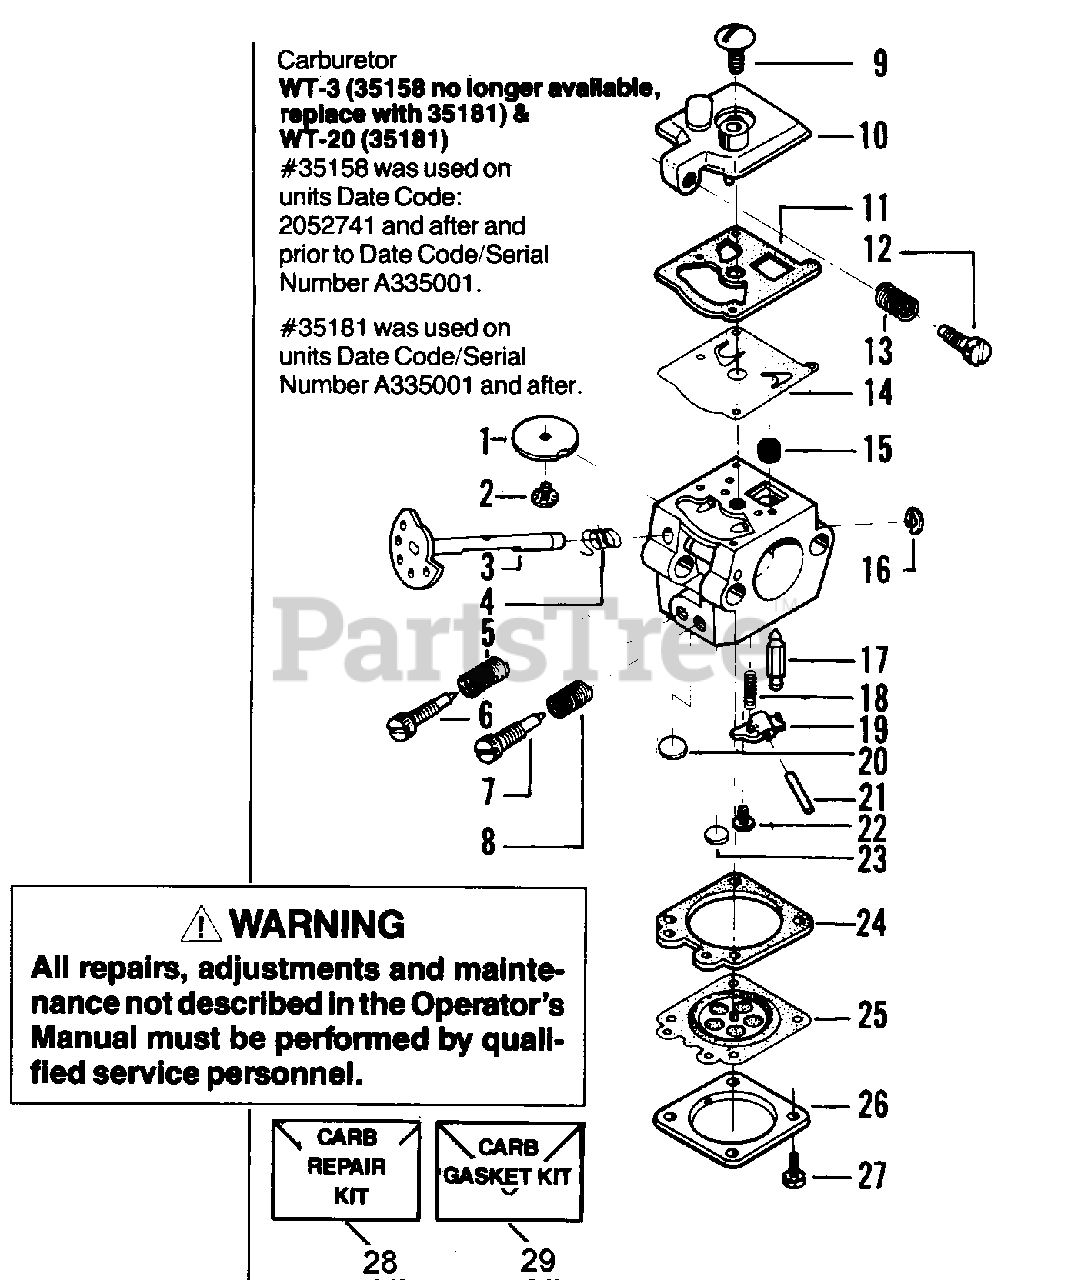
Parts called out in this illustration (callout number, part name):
1	Valve-Throttle
2	Screw-Throttle Valve
3	Shaft Assembly-Throttle
4	Spring-Throttle Return
5	Spring-Low Speed Mixture Needle
6	Needle-Low Speed Mixture
7	Needle-High Speed Mixture
8	Spring-High Speed Mixture Needle
9	Screw-Pump Cover
10	Cover-Fuel Pump
11	Gasket-Fuel Pump
12	Screw-Idle Speed Adjusting
13	Spring-Idle Speed Adjustment Screw
14	Diaphragm-Fuel Pump
15	Screen-Fuel Inlet WT-3 (# 35158)
15	Screen-Fuel Inlet WT-20 (# 35181)
16	Ring-Throttle Retainer
17	Valve-Inlet Needle
18	Spring-Metering Lever
19	Lever-Metering
20	Plug-5/16 Dia. Welch
21	Pin-Metering Lever
22	Screw-Metering Lever Pin
23	Plug 1/4 Dia. Welch
24	Gasket-Metering Diaphragm
25	Diaphragm-Metering
26	Cover Metering Diaphragm
27	Screw-Assembly Metering Cover
28	Kit-Carb Repair (Inc.11,14,15,15,17,18,19,20, 21,22,23,24,25)
29	Kit-Carb. Gasket Diaphram
